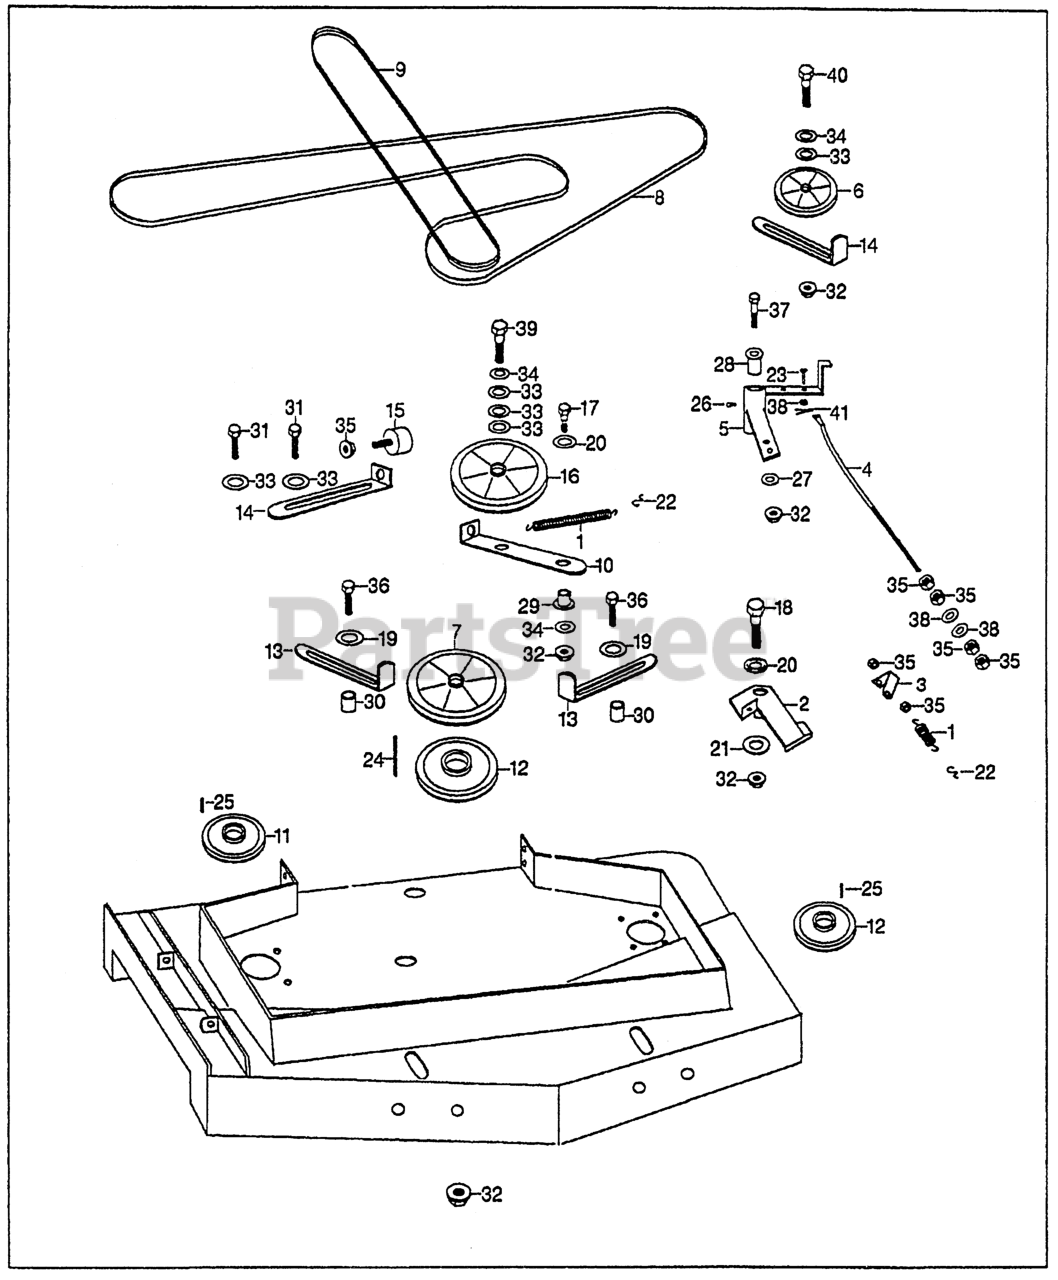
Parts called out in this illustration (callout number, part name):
1	SPRING, TENSIONER
2	BRAKE ASSY.
3	BRACKET, SPRING
4	ROD C, P.T.O. (48")
5	ARM, TENSIONER
6	PULLEY A, TENSION
7	KIT, DECK PULLEY
8	V-BELT, BLADE
9	V-BELT, DECK
10	ARM, IDLER
11	PULLEY KIT A
12	PULLEY KIT B
13	GUIDE A, BELT
14	GUIDE B, BELT
15	BUMPER, BLADE (NOT AVAILABLE)
16	PULLEY, TENSION
17	BOLT A, SHOULDER
18	BOLT B, SHOULDER
19	WASHER
20	WASHER, BELLEVILLE (1/2") Use up to Frame SN 1000677.
21	WASHER (5/16")
22	CLIP, SPRING
23	PIN, PIVOT
24	KEY A, DRIVEN PULLEY
25	KEY, SQUARE (1/4"X1/4"X1")
26	NIPPLE, GREASE
27	BUSHING (1")
28	BUSHING, PIVOT
29	BUSHING, SNAP
30	COLLAR B, SPACER
